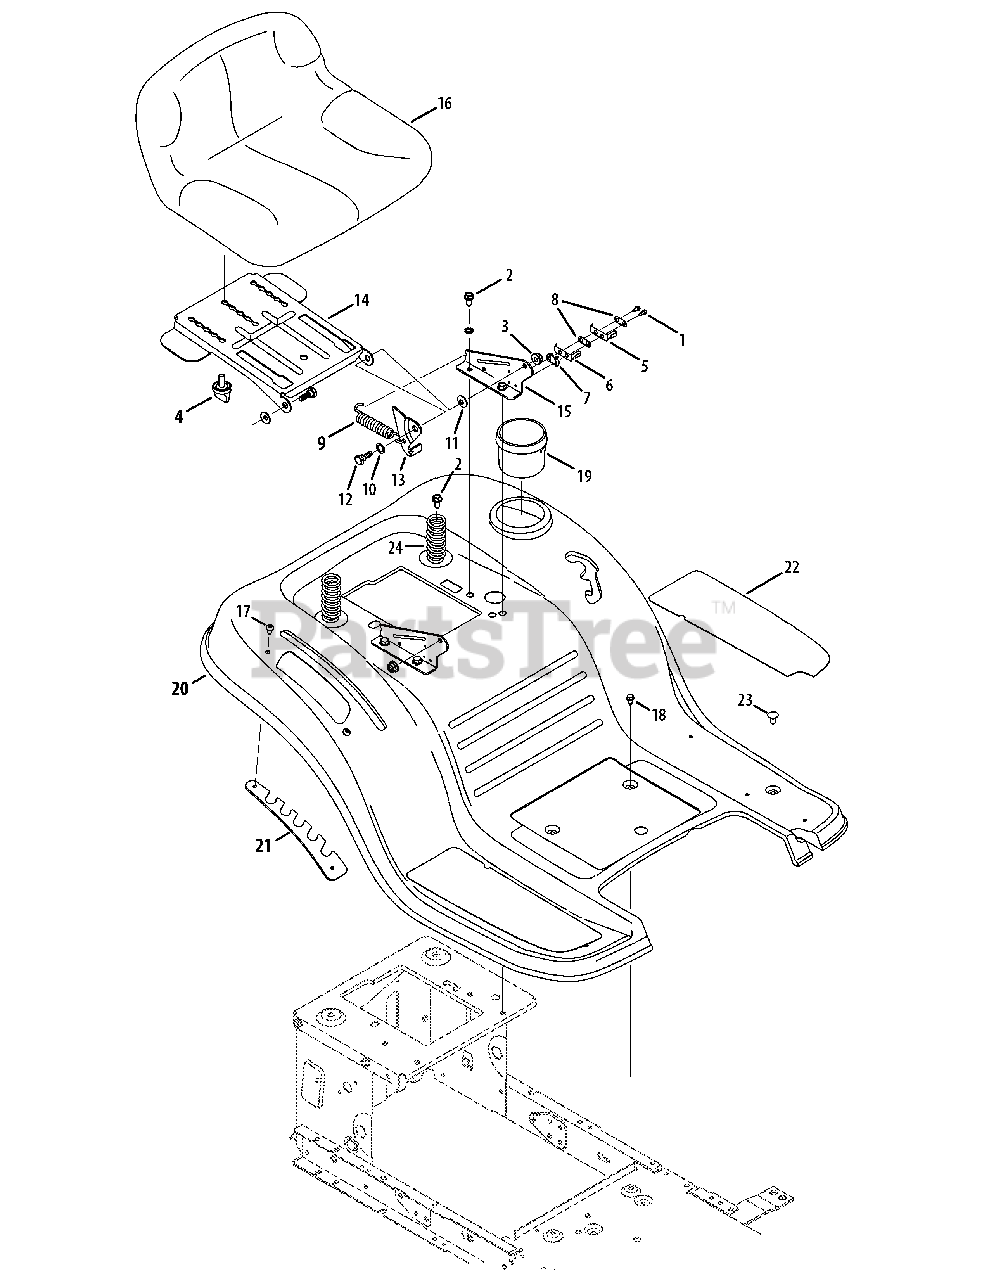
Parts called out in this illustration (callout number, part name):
1	Screw, 8-18 x .500
2	Screw, 5/16-18 x .750
3	Flange Lock Nut, 5/16-18
4	Knob, 3/8-16 x .875
5	Outer Seat Spring
6	Inner Seat Spring
7	Insulator Boss Plate
8	Insulator Plate
9	Extension Spring
10	Flat Washer, .510 x .750 x .033
11	Flat Washer, .340 x .872 x .060
12	Shoulder Screw, 5/16-18 x .437 x .268
13	Lift Seat Bracket
14	Seat Pivot Bracket
15	Seat Mounting Bracket
16	Low Back Seat
17	Screw, 1/4-20 x .500
18	Screw Pan Torx Head, 1/4-20 x .500
19	Cup Holder
20	Fender
21	Lift Adjuster Bracket
22	Abrasive Foot Pad, LH
22	Abrasive Foot Pad, RH
23	Carriage Screw, .62: 1/4-20
24	Spring, Compress., 1.28 x 3.125
